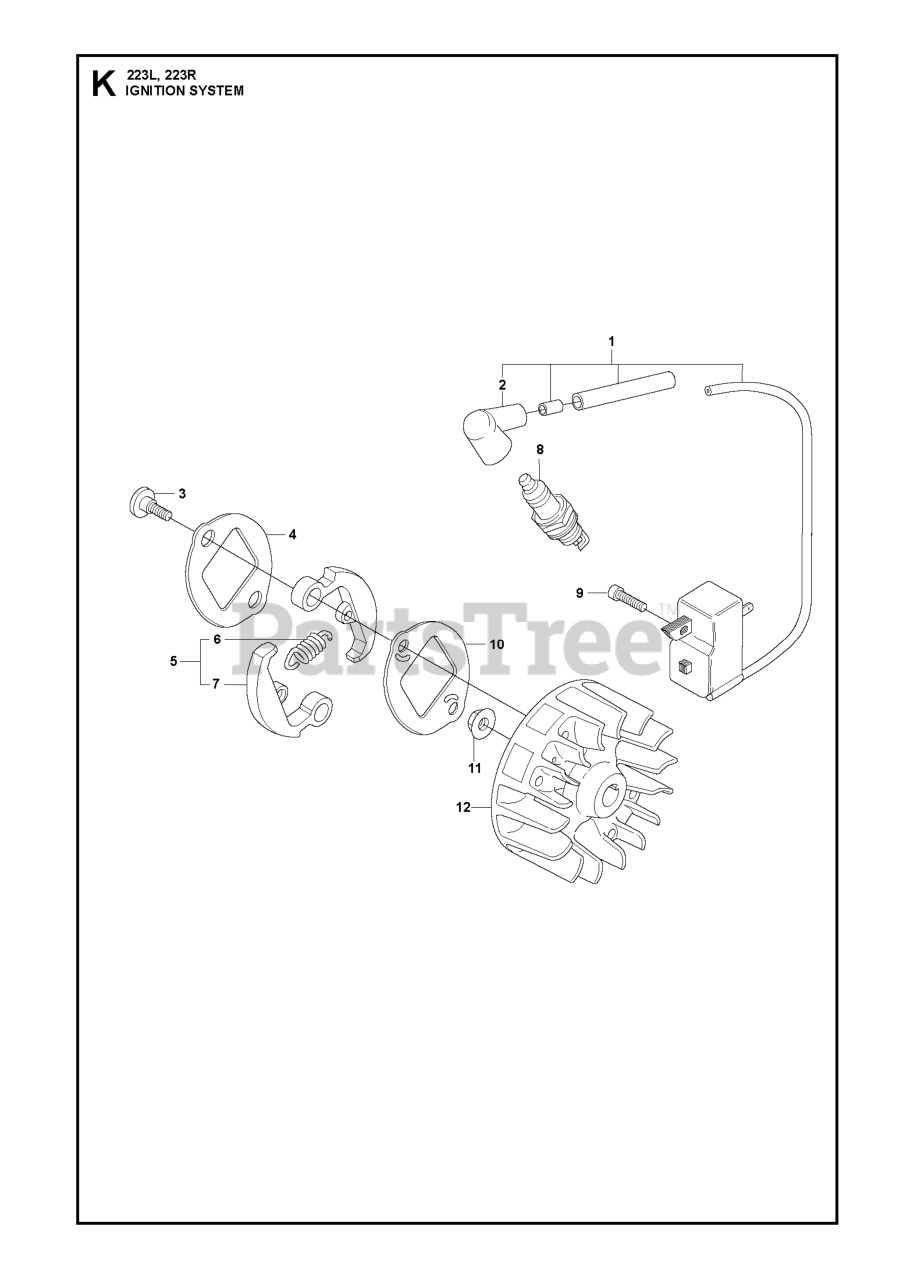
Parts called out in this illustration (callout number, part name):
1	IGNITION MODULE MB50
2	SPARK PLUG CONNECTION
4	WASHER
8	SPARK PLUG RCJ7Y
8	SPARK PLUG M14X1.25 NGK BPMR7A
9	SCREW
10	WASHER
11	FLANGE NUT
